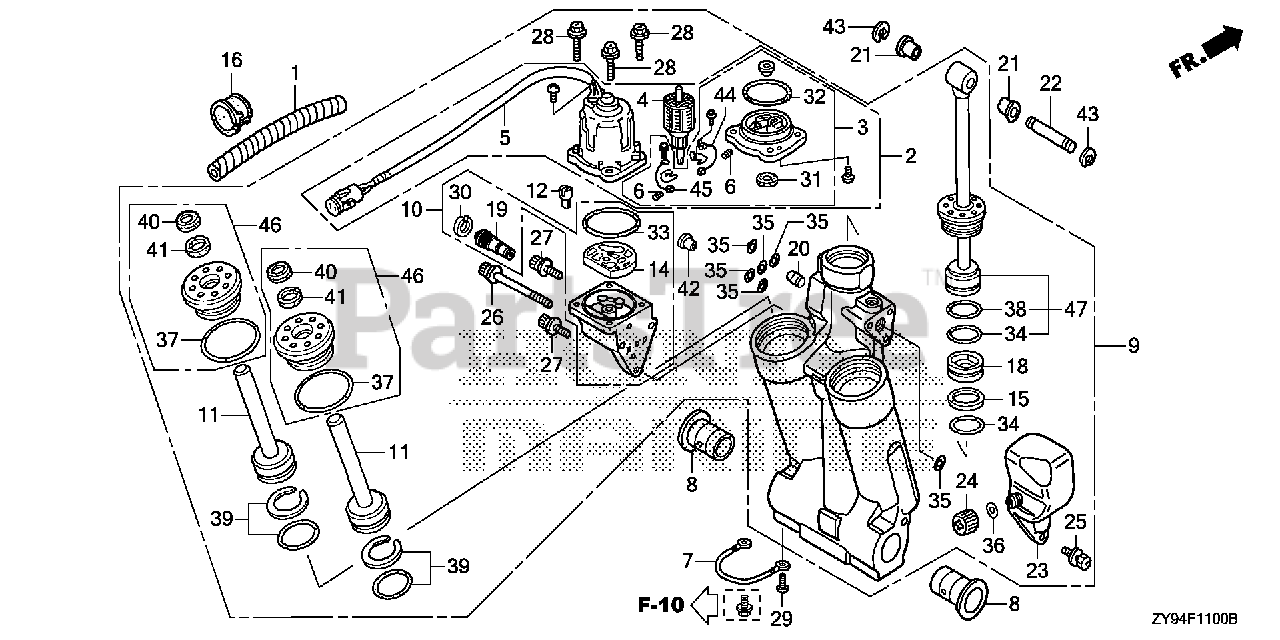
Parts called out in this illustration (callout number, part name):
1	TUBE, SPIRAL (12X14.6)
2	MOTOR ASSY., POWER TILT
3	BRACKET ASSY.
4	ARMATURE
5	YOKE ASSY.
6	SPRING, MOTOR
7	WIRE, LEAD (1.5X116MM)
8	BUSH, SWIVEL CASE
9	TRIM-TILT ASSY., POWER
10	PUMP ASSY.
11	ROD, PISTON (B)
12	JOINT, DRIVE
14	FILTER (B)
15	RING, BACK-UP
16	BUSH, MOTOR CODE
18	PISTON, FREE
19	VALVE, MANUAL
20	VALVE, RESERVOIR
21	BUSH, CYLINDER (LOWER)
22	PIN, CYLINDER (UPPER)
23	TANK, OIL
24	CAP, OIL TANK
25	BOLT, RECESSED
26	BOLT A, SOCKET
27	BOLT B, SOCKET
28	BOLT, HEX.
29	SCREW, PAN (6X8)
30	CIRCLIP (INNER)
32	O-RING (2.0X70.5)
33	O-RING (1.8X69.6)
34	O-RING (3.5X38.7)
35	O-RING (1.8X7.7)
36	O-RING (1.9X11)
37	O-RING (3.5X35.7)
38	O-RING (3.5X41.7)
39	O-RING SET (3.5X31.7)
40	SEAL, WATER
42	COLLAR, ORIFICE
43	E-RING (15MM)
44	BREAKER ASSY.
45	BRUSH ASSY.
46	GUIDE, ROD
47	ROD, PISTON
